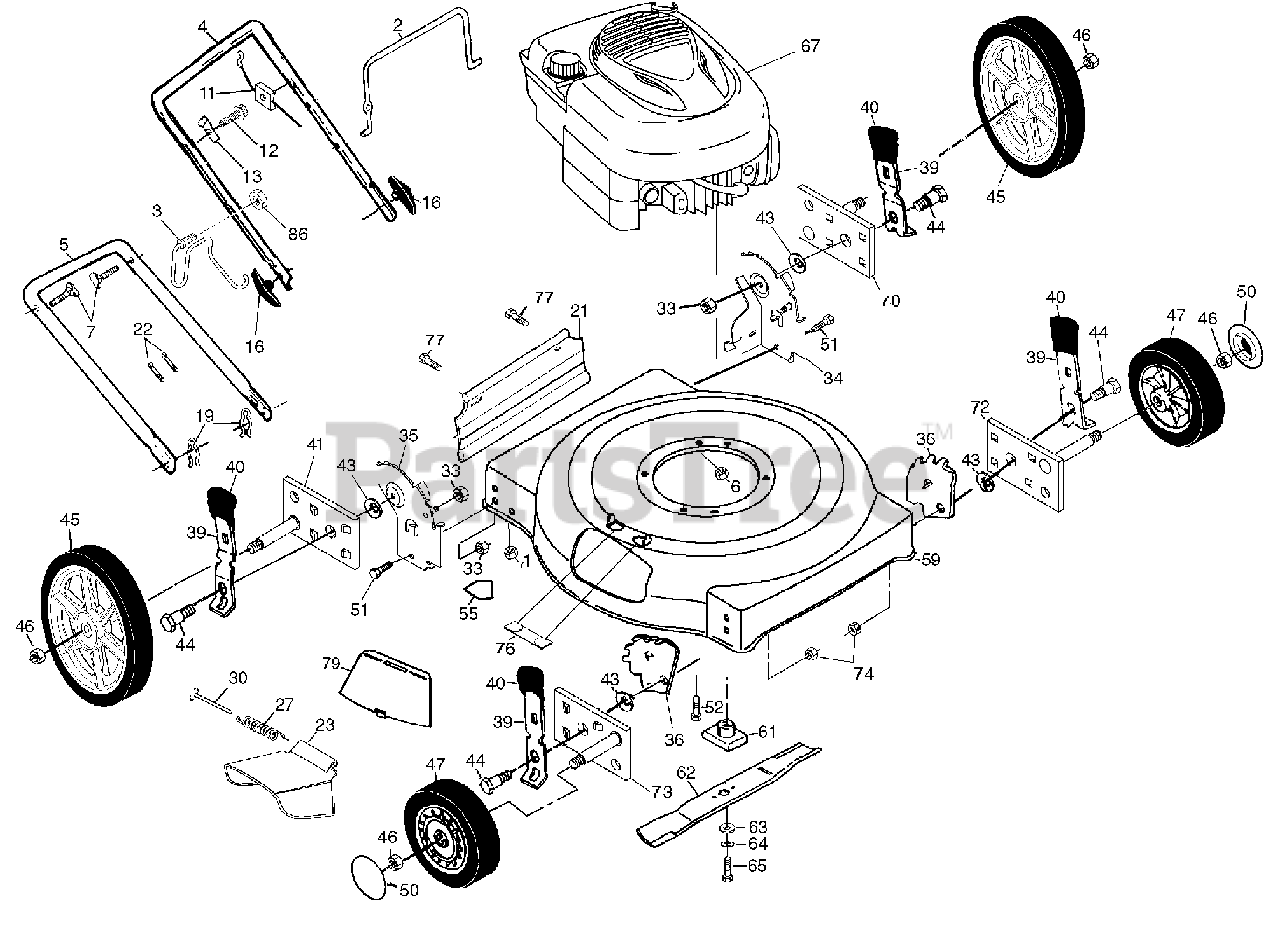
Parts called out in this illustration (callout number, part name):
1	Locknut 1/4-20
2	Control Bar
3	Rope Guide / Anti-Fold Bracket
4	Upper Handle
5	Lower Handle
7	Handle Bolt 5/16-18
11	Engine Zone Control Cable
12	Hex Washer Head Screw #10-24 x 1/2
13	Up-Stop Bracket
16	Handle Knob
19	Hairpin Cotter
21	Rear Deflector
22	Wire Tie
23	Discharge Guard
27	Torsion Spring
30	Hinge Rod
33	Locknut 5/16-18
34	Wheel Bracket Support (Left)
35	Wheel Bracket Support (Right)
36	Wheel Bracket Adjuster
39	Selector Spring
40	Selector Knob
41	Axle Arm Assembly (RR)
43	Washer
44	Shoulder Bolt
45	Wheel Assembly (Rear)
46	Locknut 1/16-18
47	Wheel Assembly (Front)
50	Hubcap
51	Hex Head Bolt 5/16-18
52	Hex Head Thread Rolling Screw 3/8-16 x 1
55	Danger Decal
59	Lawn Mower Housing
61	Blade Adapter
62	22" Blade
63	Hardened Washer
64	Helical Lockwasher 3/8
65	Screw Hex Head 3/8-24 x 1-3/8 (Grd. 8)
70	Axle Arm Assembly (LR)
72	Axle Arm Assembly (LF)
73	Axle Arm Assembly (RF)
74	Nut
76	Clip, Closeout
77	Screw
79	Mulch Plate
86	Operator's Manual (English)
86	Operator's Manual (French)
86	Replacement Parts Manual
